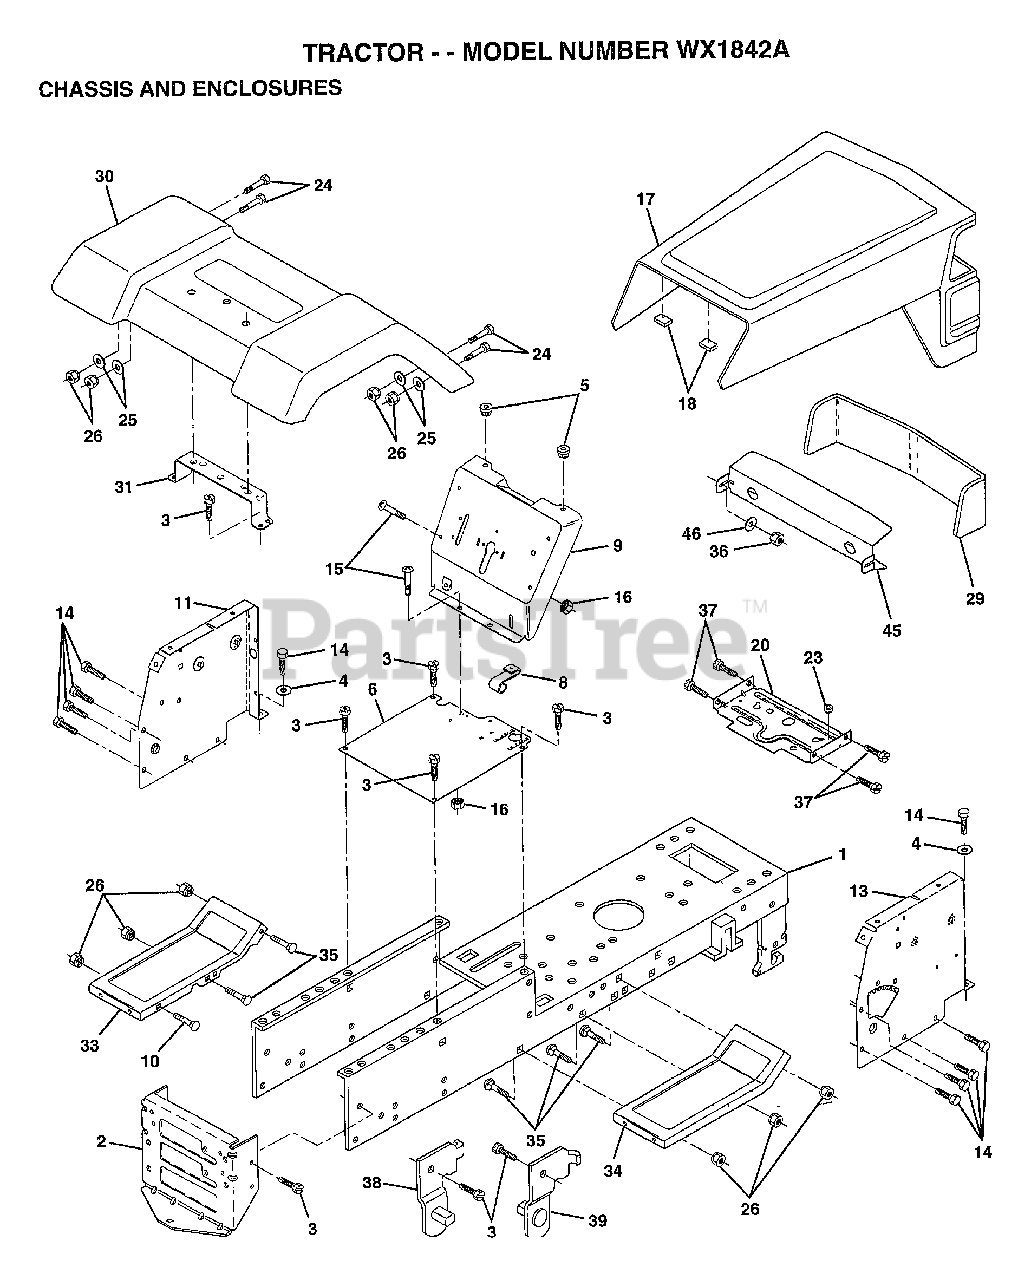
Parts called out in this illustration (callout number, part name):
1	CHASSIS.WLD.11GA
3	SCREW
4	WASHER
8	"CLIP,INSULATOR"
9	DASH.SLKSC.LT.1PC
11	DASH PANEL LH
14	SCREW LT
15	SCREW
17	HOOD/GRILLE.ASM
20	PLATE.MTG.BTRY.TK
24	BOLT
25	WASHER
26	NUT
31	BRKT FENDER
33	FOOTREST.LH.LT/GT
34	FOOTREST.RH.LT/GT
35	BOLT
36	PAL NUT LT
37	SCREW
38	BRACKET ASM LH
39	BRACKET ASM RH
46	RETAINER
